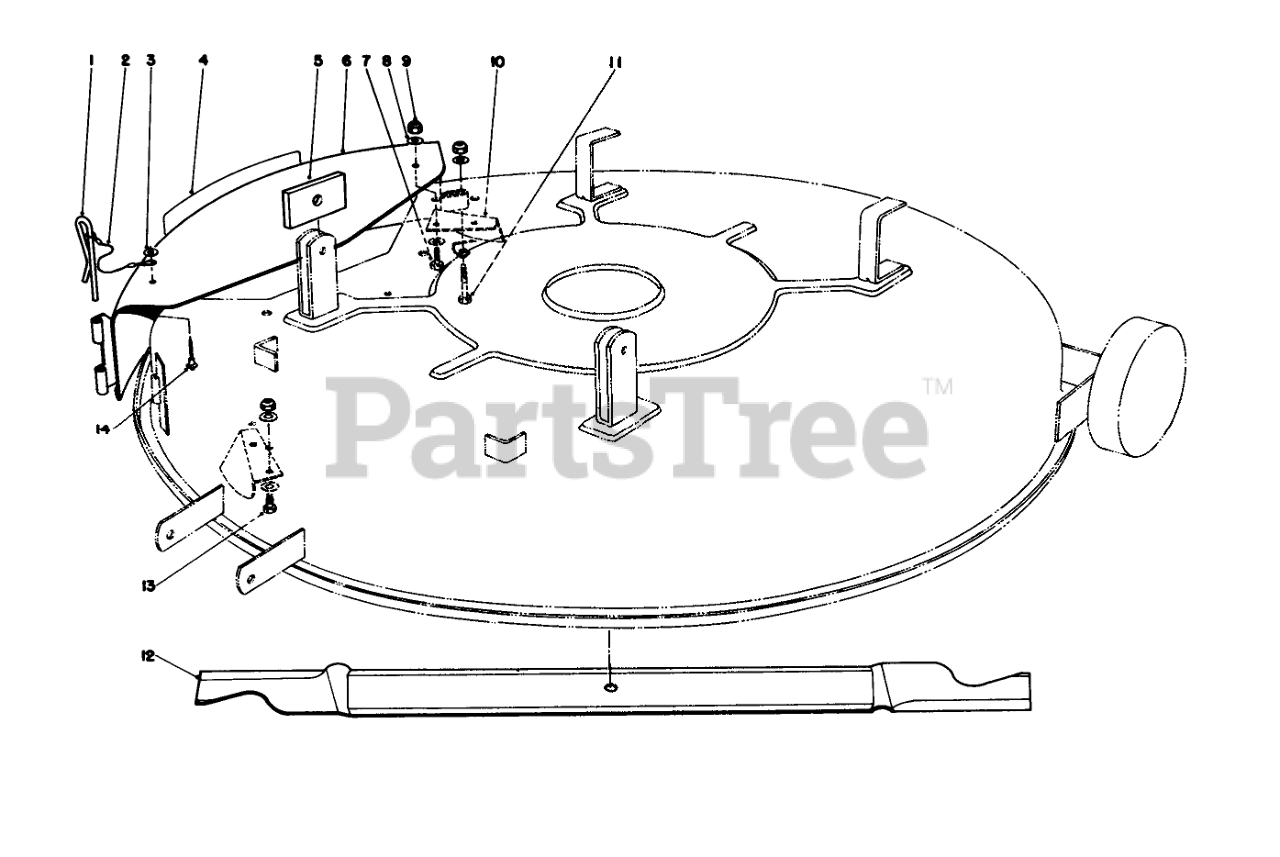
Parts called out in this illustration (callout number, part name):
1	PIN-LOCKING, CHUTE
2	LANYARD
3	WASHER-PLAIN
4	COVER DECAL
5	SPACER
6	Cover-Mulcher Assembly (Incl. Ref. #1-4 & 14)
7	SCREW-HH
8	WASHER-PLAIN
9	NUT-LOCK, NI
10	KICKER B
11	SCREW-HH
12	Blade
13	SCREW-HH
14	RIVET-BLIND
